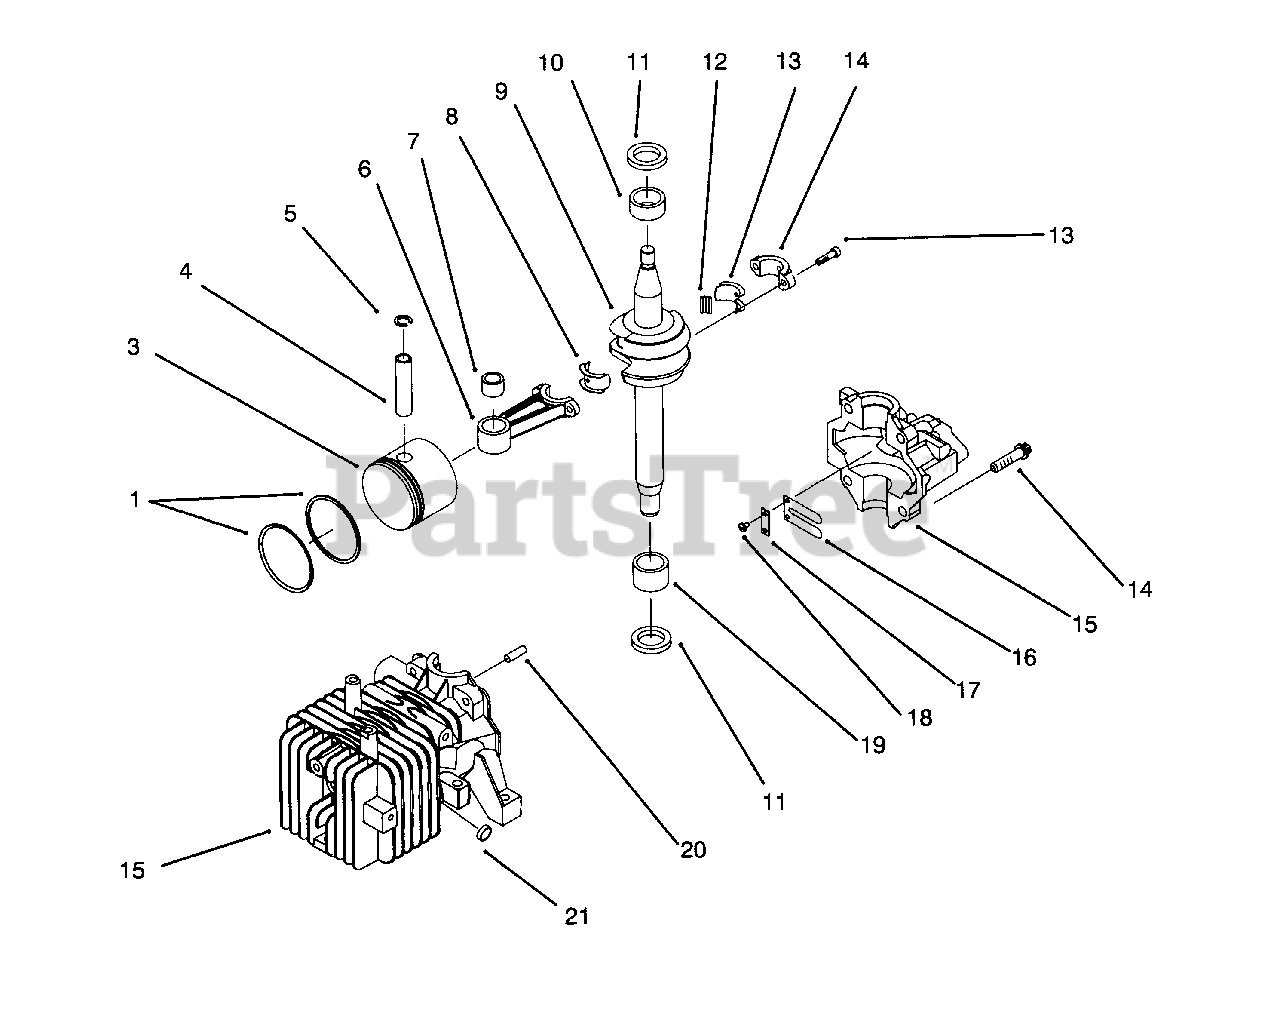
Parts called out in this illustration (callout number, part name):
1	Piston & Ring Set
4	Pin-Wrist
5	Ring-Retaining
6	Connecting Rod Assembly(Incl. Ref. #8 & 13)
8	Liner-Split (Set of 2)
9	Crankshaft
10	Bearing-Upper Main
11	Seal-Oil
12	Bearing-Needle
13	Screw-Hex Hd.
14	Screw-Hex Washer Hd.
15	Cylinder & Crankcase Cover
16	Reed-Carburetor
17	Reed-Backup Plate
19	Bearing-Needle
21	Plug-Core
